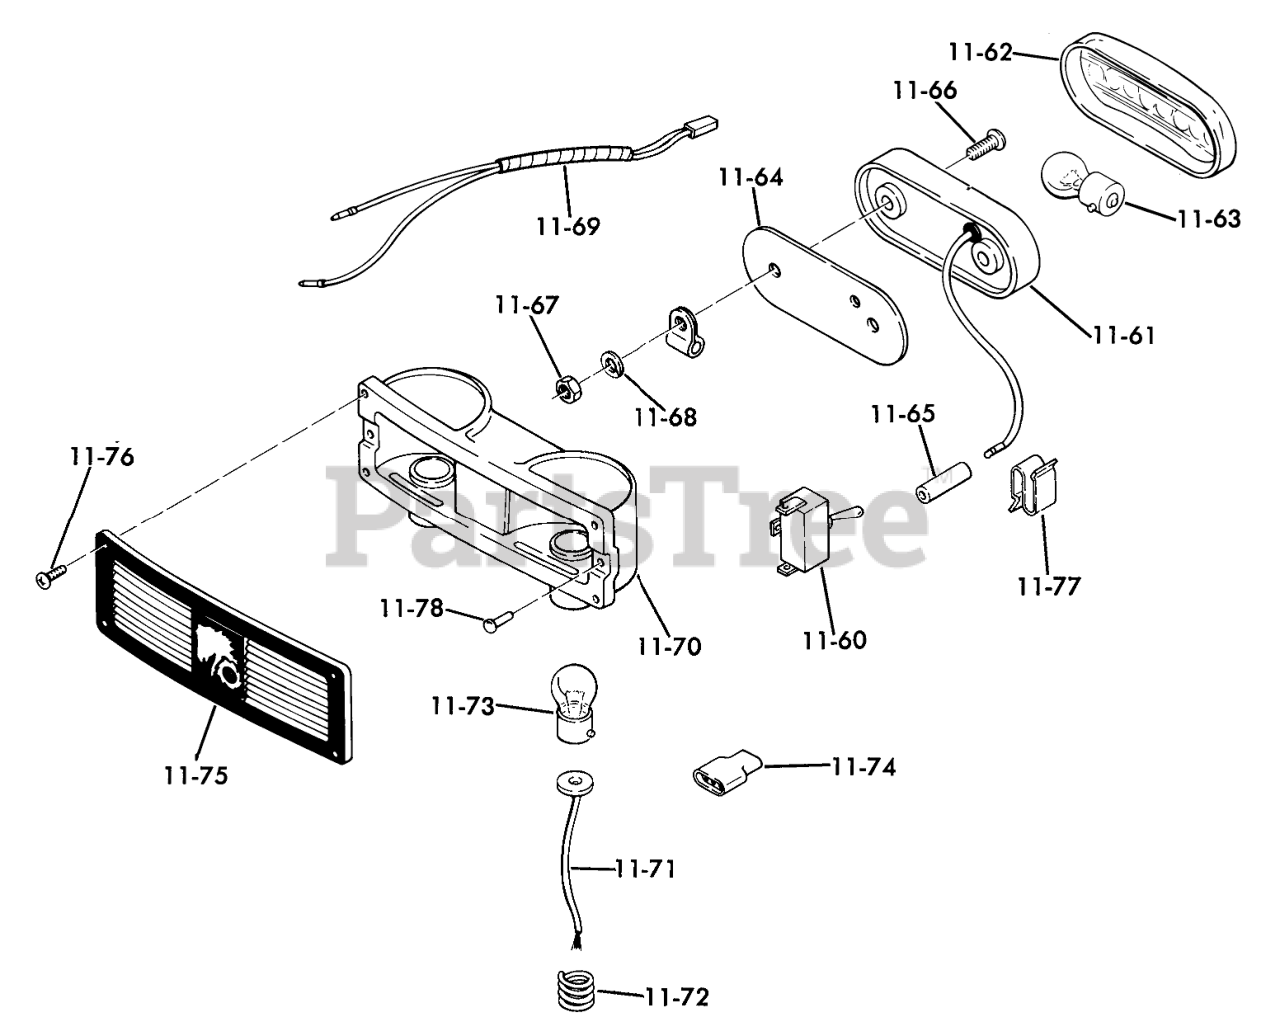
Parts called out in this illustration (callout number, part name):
11-60	SWITCH-LIGHTS
11-61	Tail Light Base (w/Bulb)
11-62	Red Tail Light Lens
11-63	Tail Light Bulb
11-64	Tail Light Mounting Pad
11-65	Cap-Fuel Tank
11-66	Pan Hd. Bolt #10-32 x 5/8
11-67	Hex Nut #10-32
11-68	Lockwasher
11-69	Wire Harness-Lights
11-70	ASSY REFLECTOR HOUSI
11-71	WIRE ASSY
11-72	SPRING
11-73	BULB
11-74	CONNECTOR 3 WIRE
11-75	Lens
11-76	Pan HD Swage
11-77	SPEED CLIP
11-78	RIVET
